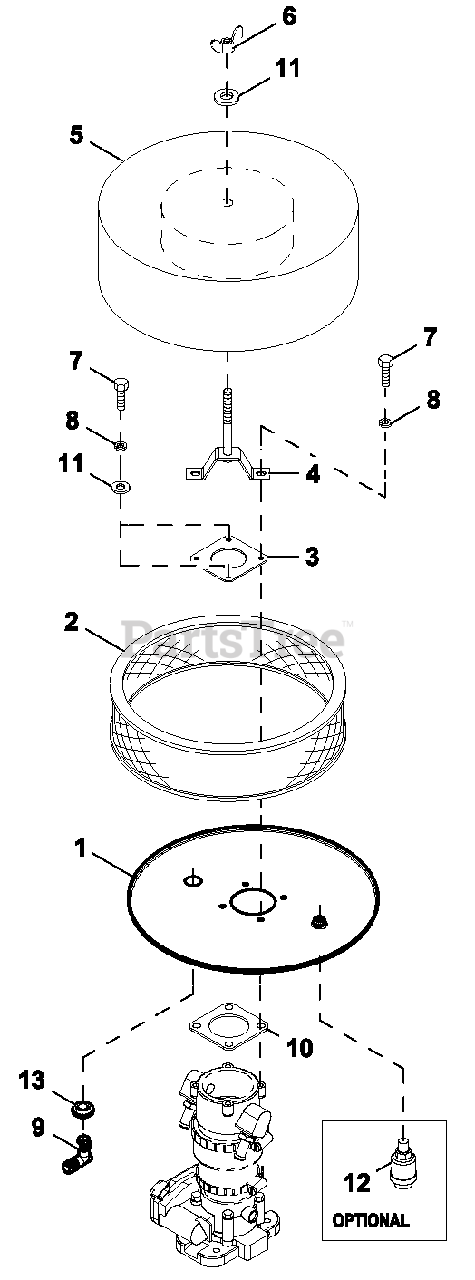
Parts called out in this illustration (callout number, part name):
1	AIR CLNR BTM PLT W/CPLR 8.1 L
2	ELEMENT AIR FILTER
3	TOP PLATE VENTURI
4	HOLD DOWN AIR CLEANER PLATED
5	PLATE AIR CLEAN TOP 5.4L/6.8L
6	NUT WING 1/4-20 NYLK
7	SCREW HHC M6-1.0 X 16 G8.8
8	WASHER LOCK M6-1/4
9	BARBED EL 90 5/8 PLASTIC
10	GASKET MIXER BODY
11	WASHER FLAT 1/4-M6 ZINC
12	INDICATOR FILTER MINDER (USE WITH ITEM #1 P/N 0D2513E)
13	GROMMET .625 X 1.25 X .433
